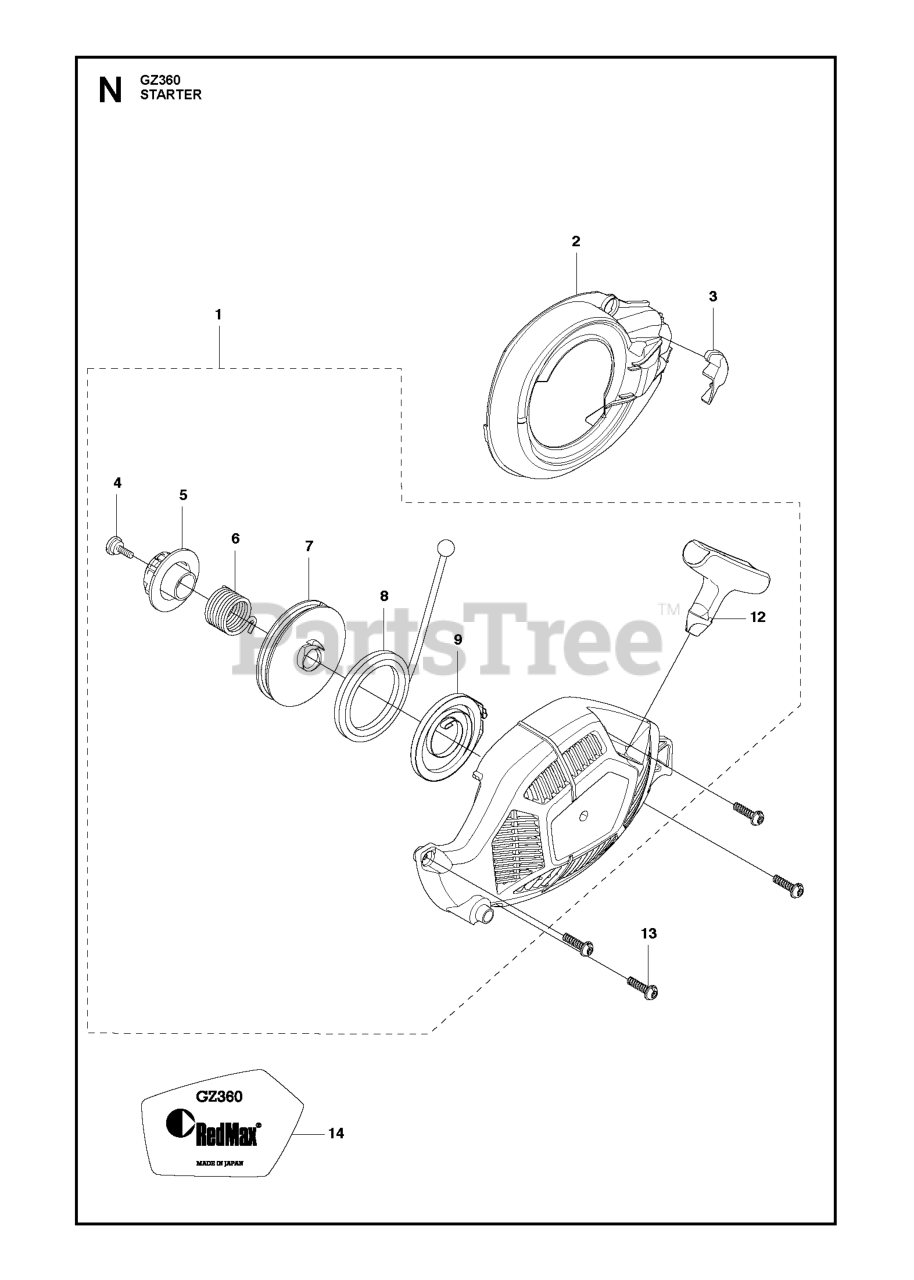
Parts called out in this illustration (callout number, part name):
1	STARTER ASSY GZ3500L
2	COVER FAN
3	GUIDE, DF (GZ3500T)
5	CAM, PLATE
9	SPRING ASSY
12	STARTER HANDLE
14	DECAL STARTER
